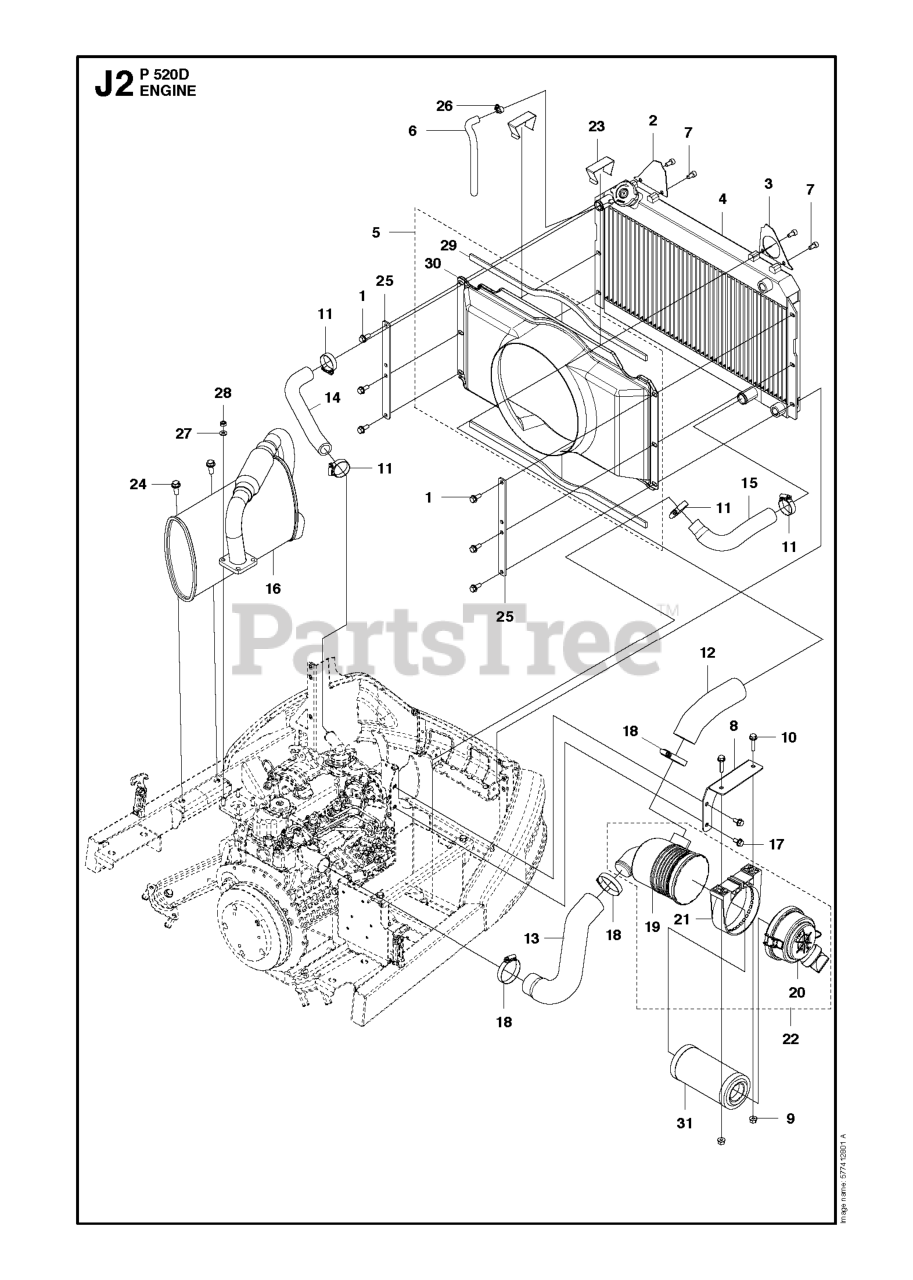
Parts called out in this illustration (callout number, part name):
9	NUT FLANGE
10	SCREW EHHFM
20	AIR FILTER END COVER
26	RP HOSE CLAMP FUEL HOSE
27	WASHER BRB 8.4X17
28	NUT
31	AIR FILTER
